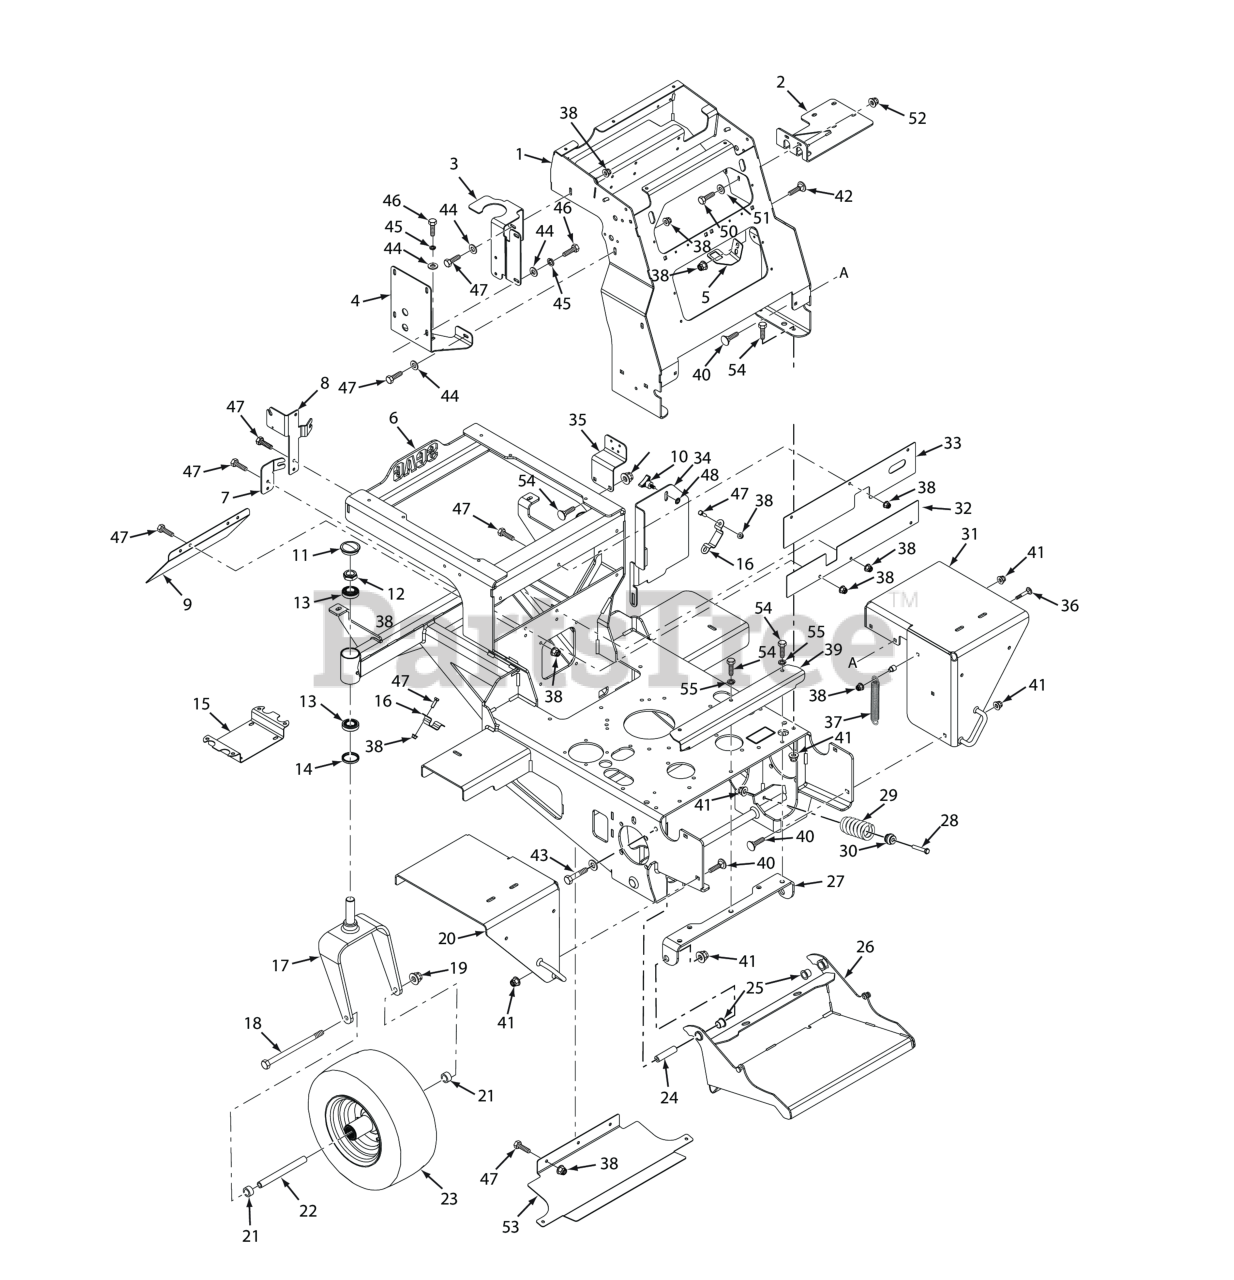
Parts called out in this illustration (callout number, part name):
1	Handlebar Weldment
2	Mounting Bracket, Hose Reel
3	Mounting Bracket, Oil Reservoir
4	Mounting Bracket, Fuel Tank
5	Mounting Bracket, Brake Switch
6	Mainframe Weldment, STS
7	Mounting Bracket, Door Cable
8	Mounting Bracket, Cable
9	Cover, Vent
10	Knob, w/ Stud, 5/16 - 18
11	Cap, Grease
12	Nut, Elastic Stop 1.0"-14
13	Bearing Set
14	Seal, 2.00" O.D. x 1.625" Bore
15	Mounting Bracket, Foamer Accessory (optional)
16	Bracket, Hose
17	Caster Yoke Weldment
18	Bolt, Hex Head 1/2-13 x 9-1/2" (61V & 72A/VS)
19	Nut, Elastic Stop 1/2-13, (STT-52 & STTII-52)
20	Fender, LH
21	Spacer, Caster Wheel
22	Sleeve, Caster Wheel (61V, 72A/VS)
23	Caster Wheel Assembly, 16 x 6.50 - 8
24	Spacer
25	Bearing, .750 I.D. Plastic
26	Footplate Assembly (Incl. #25)
27	Footplate Weldment
28	Bolt, Hex Head 3/8-16 x 2-1/4" - Stainless Steel
29	Spring, Suspension Platform
30	Mount, Spring
31	Fender, RH
32	Guard, Rear Hopper Lower
33	Guard, Rear Hopper Uppler
34	Battery Door
35	Mounting Bracket, Strainer
36	Bolt, Carriage 5/16-18 x 1.75 - Stainless Steel
37	Spring,Counter Balance
38	Locknut, 5/16-18 Flg. Elastic Stop - Stainless Steel
39	Mounting Bracket, Operator Presence
40	Bolt, Carriage 3/8-16 x 1.0 - Stainless Steel
41	Nut, Flange Elastic Stop 3/8 - 16 - Stainless Steel
42	Bolt, Carriage 5/16 - 18 x 1" - - Stainless Steel
43	Bolt, Hex 3/8 - 16 x 4.00 - Stainless Steel
44	Washer, Flat 5/16 -.375 x .875 x .0547/.104 - Stainless Steel
45	Washer, Lock 5/16 Spring - Stainless Steel
46	Bolt, Hex 5/16 - 18 x .75 - Stainless Steel
47	Bolt, Hex 5/16" - .375 x 1.00- Stainless Steel
48	Nut, Push On - Stainless Steel
49	Spring Bracke, Footplate
50	Bolt, Hex 1/4 - 20 x 1.00
51	Locknut, 1/4 - 20 Flg. Elastic Stop - Stainless Steel
52	Washer, Flat 1/4-.281X.625X.080 - Stainless Steel
53	Muffler Heat Shield
54	Bolt, Hex Head 3/8 - 16 x 1.50 - Stainless Steel
55	Lockwasher, 3/8-.377 x .680 x 094
